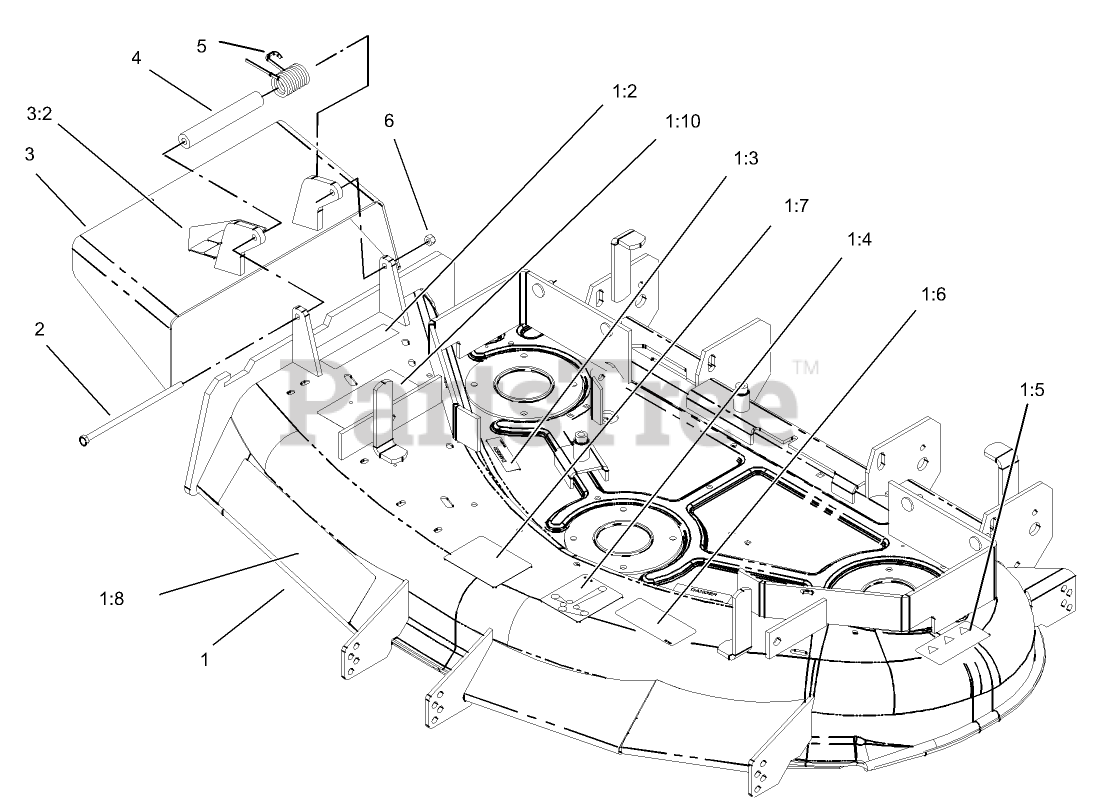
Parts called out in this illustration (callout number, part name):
1	Deck ASM W/Decals
1:2	DECAL-WARNING, DEFLECTOR
1:3	DECAL-WARNING
1:4	DECAL-ROUTING, BELT
1:5	DECAL-DANGER
1:6	DECAL-TORQUE, BLADE BOLT
1:7	DECAL-ANTI SCALP
1:10	DECAL-DANGER
2	SCREW-HH
3	Deflector ASM
3:2	DECAL-DANGER
4	SPACER
5	SPRING-TORSION
6	NUT-LOCK, NI
